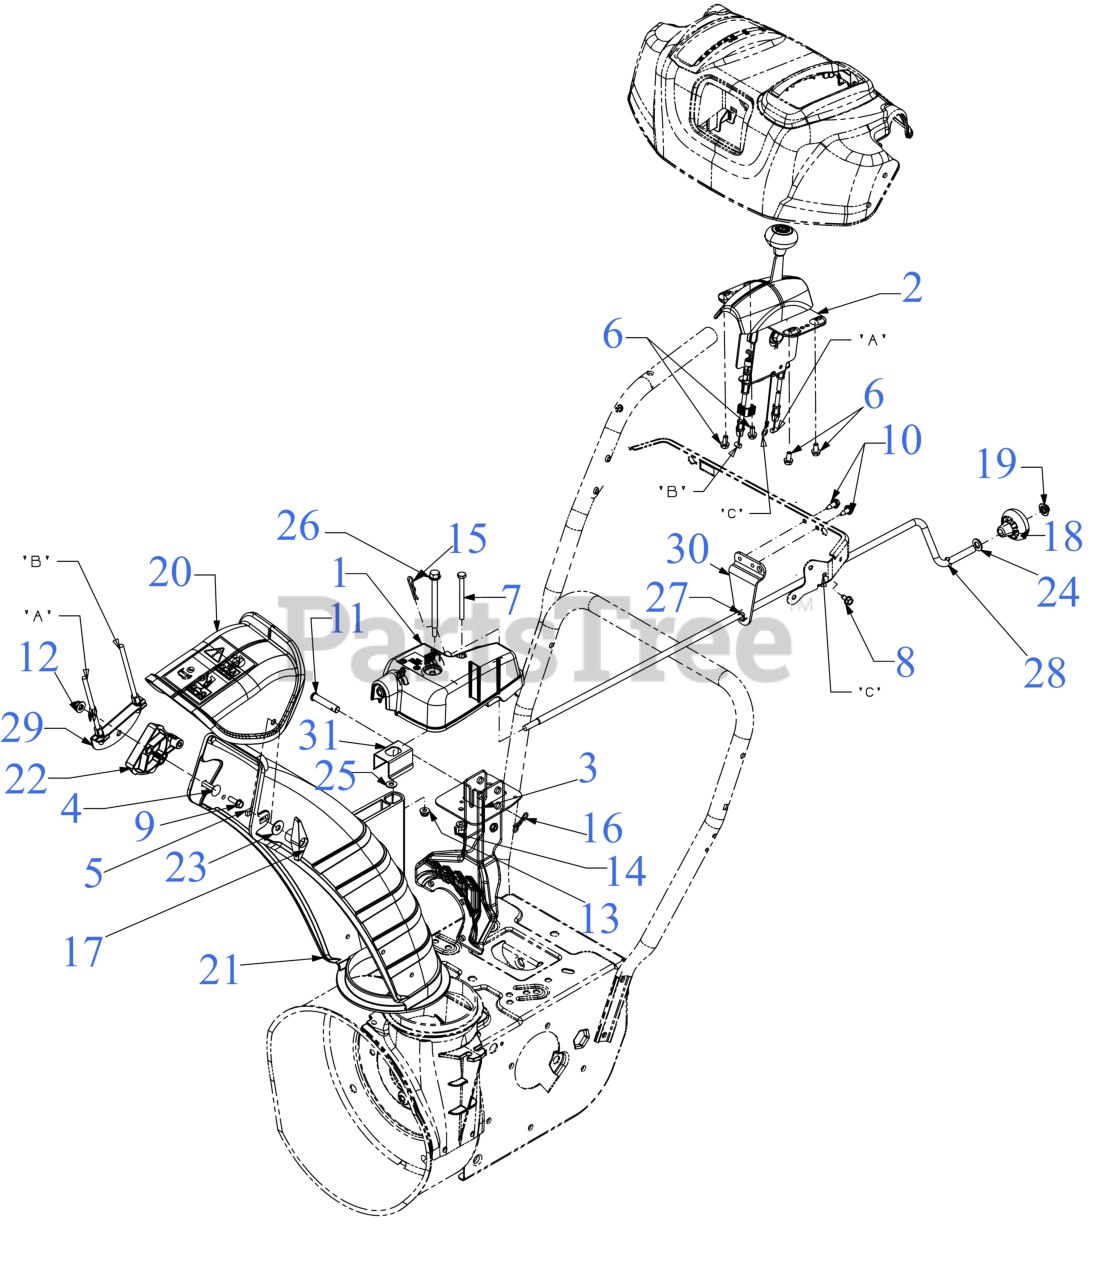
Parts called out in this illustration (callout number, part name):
1	2-WAY CHUTE ROTATE GEARBOX
2	CHUTE CONTROL ASSEMBLY TALL 2-WAY
3	CHUTE MAST
4	CARRIAGE BOLT 5/16-18 x 1.50
5	CARRIAGE BOLT 5/16-18 x 1
6	HEX SCREW 1/4-15 x .50
7	SCREW 1/4-20 x 3.0 GR5
8	SCREW 1/4-20 X.500
9	SCREW 1/4-15 x .750
10	SCREW 1/4-20X.625
11	CLEVIS PIN 3/8 x 1.87
12	FLANGE LOCK NUT 5/16-18
13	FLANGE LOCK NUT
14	WING NUT 1/4-20
15	INTERNAL COTTER PIN
16	BOW TIE COTTER PIN 1/4-5/16
17	WING KNOB NUT
17	HEX NUT
18	SHIFT KNOB
19	PUSH NUT
20	UPPER REMOTE CHUTE WITH LABEL
21	LOWER CHUTE 5"
22	CABLE CHUTE GUIDE
23	FLAT WASHER
24	FLAT WASHER
25	FLAT WASHER
26	SHOULDER SCREW
27	BUSHING .380 ID
28	CHUTE CRANK .375 DIA x 31"
30	ROD SUPPORT BRACKET
31	CHUTE BRACKET
